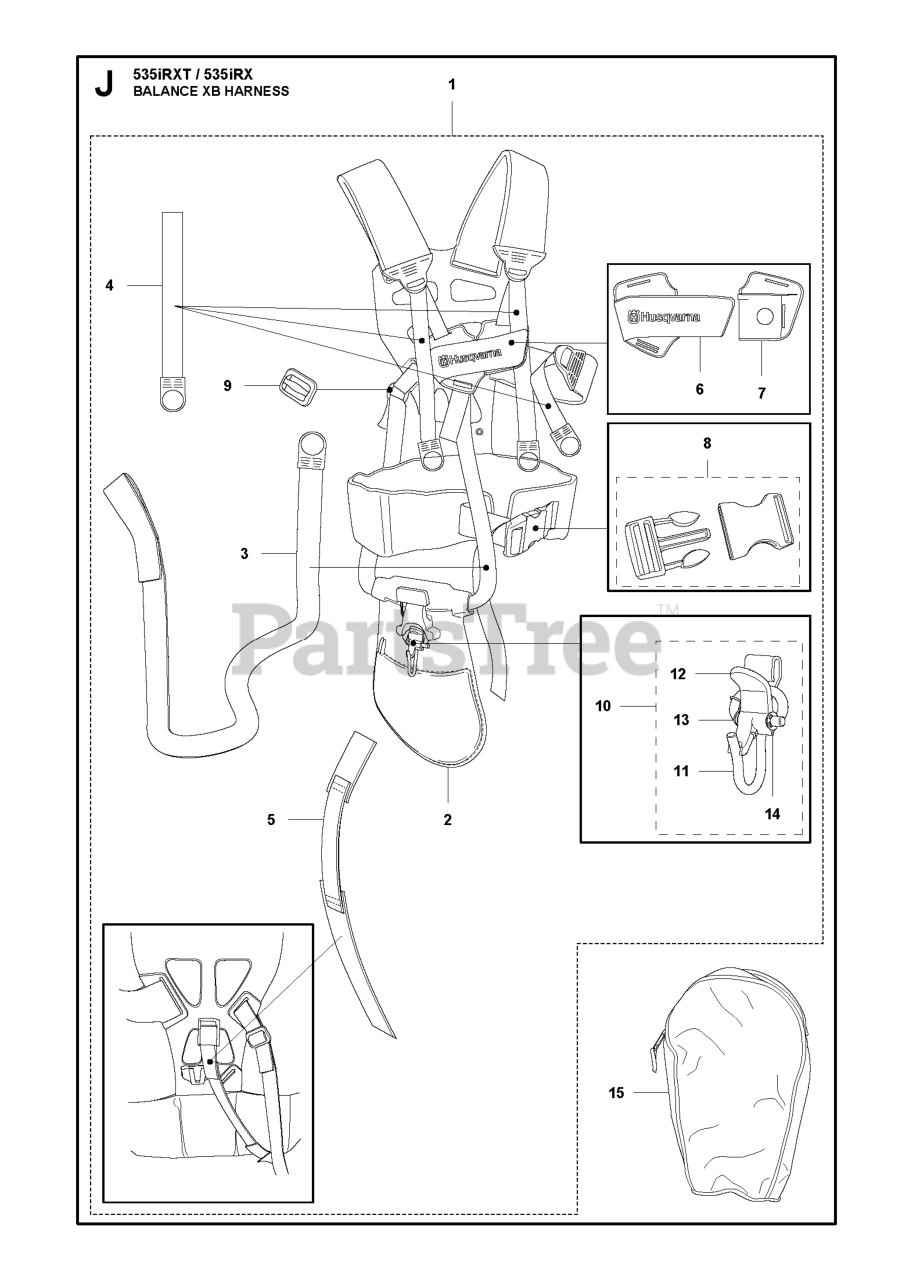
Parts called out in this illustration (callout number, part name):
1	HUS BALANCE X TRIO HARNESS
6	FRONT PIECE
7	FRONT PIECE
11	HOOK
12	CATCH *
13	SPRING LOCKING
15	TOOL BAG
